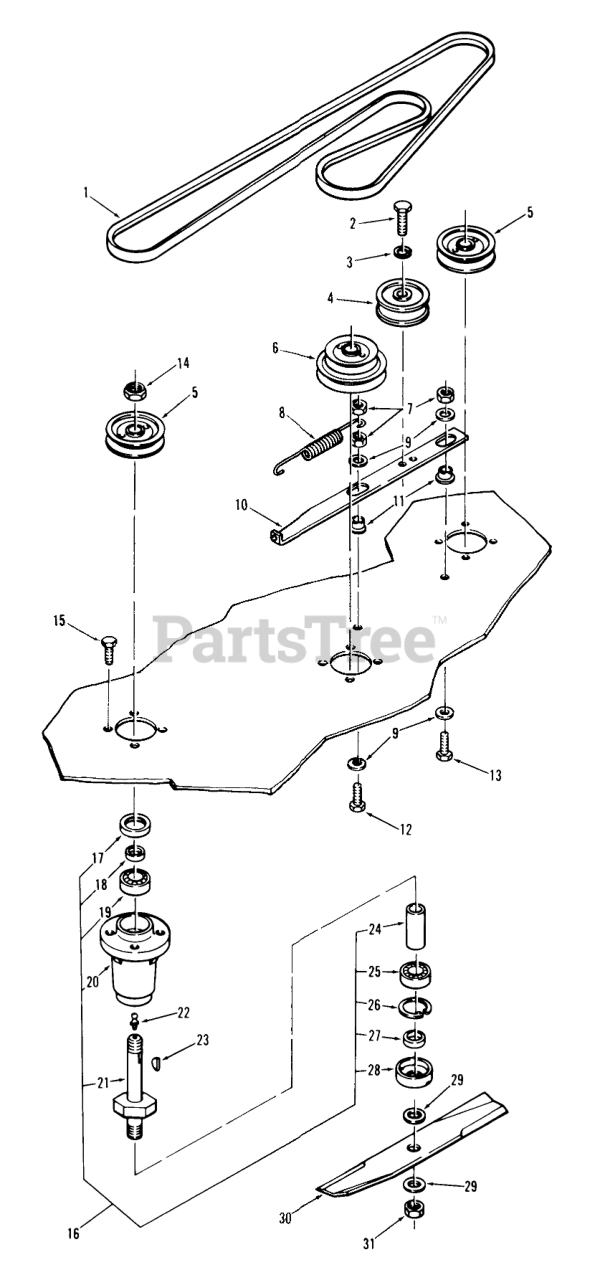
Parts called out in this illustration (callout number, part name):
1	V-BELT
2	Bolt
3	LOCKWASHER
4	Idler Pulley
5	PULLEY-BLADE DRIVE
6	PULLEY-42 MOWER SPDL
7	Nut
8	SPRING-EXTENSION
9	WASHER
10	BAR-IDLER SUPPORT
11	Bushing/Spacer
12	Bolt
13	Bolt
14	Nut
15	Bolt
16	Spindle Assembly
18	SPACER-SEAL
19	BEARING-BALL
20	HOUSING-SPINDLE
21	Spindle Shaft
22	Zerk
23	Hi-Pro Key 3/16 x 5/8
24	SPACER
25	BEARING-BALL
26	Ring-Snap
27	SPACER-BLADE
28	CUP-SPINDLE
29	Washer
30	Mower Blade
31	Nut
